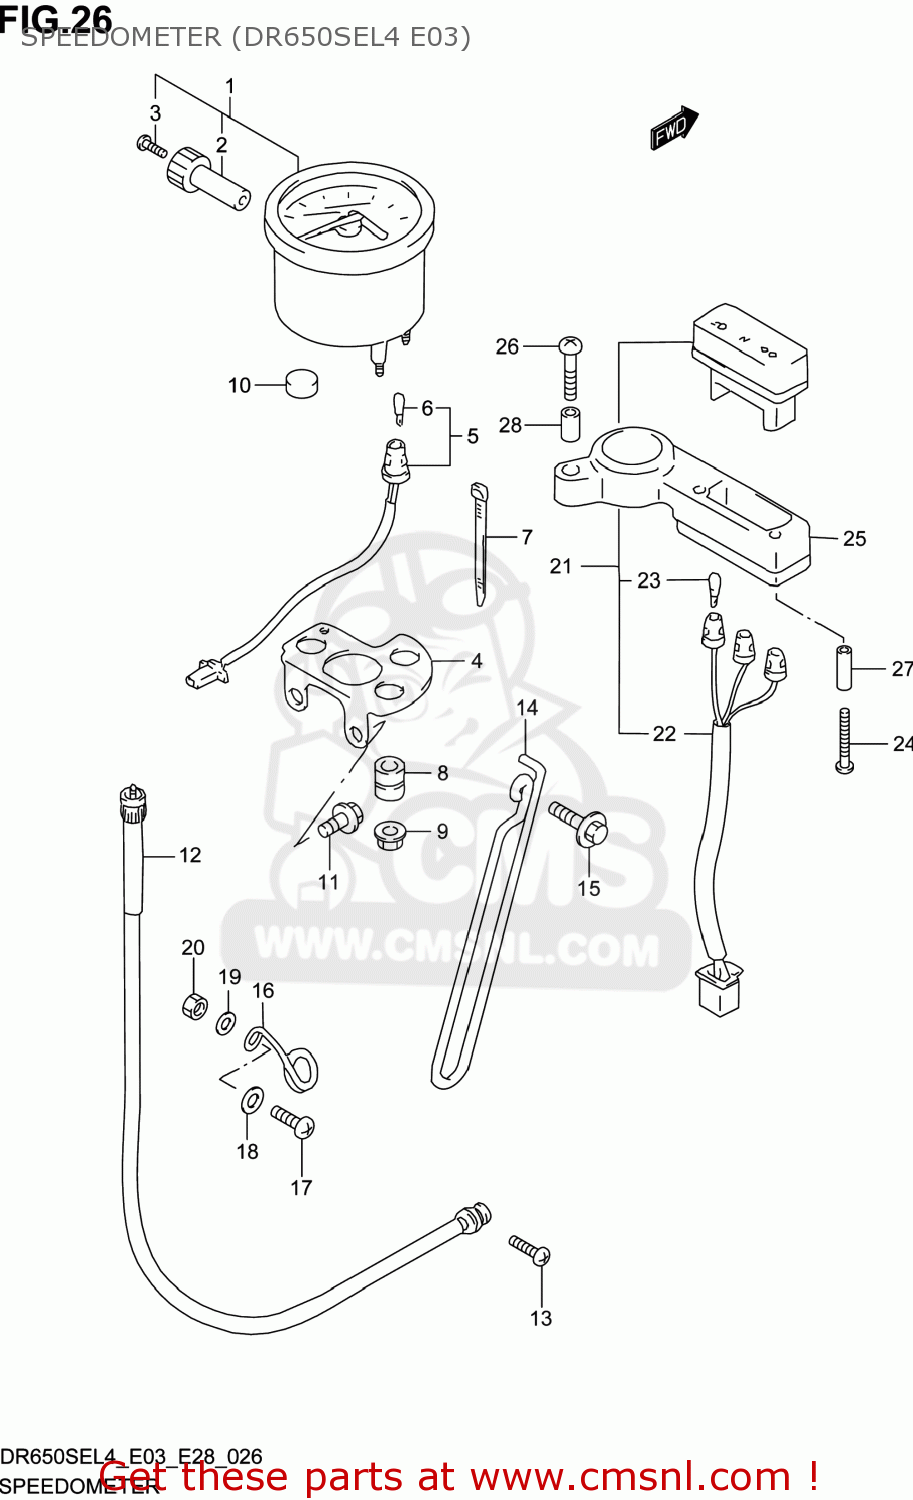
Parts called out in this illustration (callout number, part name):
1	SPEEDOMETER
2	KNOB,TRIP
3	SCREW,TRIP KNOB
4	BRACKET,METER
5	SOCKET
6	BULB(12V1.7W,T6.5)
7	CLAMP
8	CUSHION
9	NUT
10	CUSHION
11	BOLT
12	CABLE ASSY,SPEEDOMETER
13	SCREW
14	GUIDE,METER CABLE NO.2
15	BOLT(6X20)
16	GUIDE,SPEEDOMETER CABLE
17	SCREW
18	WASHER(6.5X18X1.6)
19	WASHER
20	NUT
21	BOX ASSY,PILOT LAMP
22	SOCKET & CORD
23	BULB(13.5V,2W,A7427)
24	SCREW
25	HOLDER,PILOT BOX
26	SCREW(6X25)
27	SPACER(4.5X6.5X25)
28	SPACER(6.1X8X15.5)
